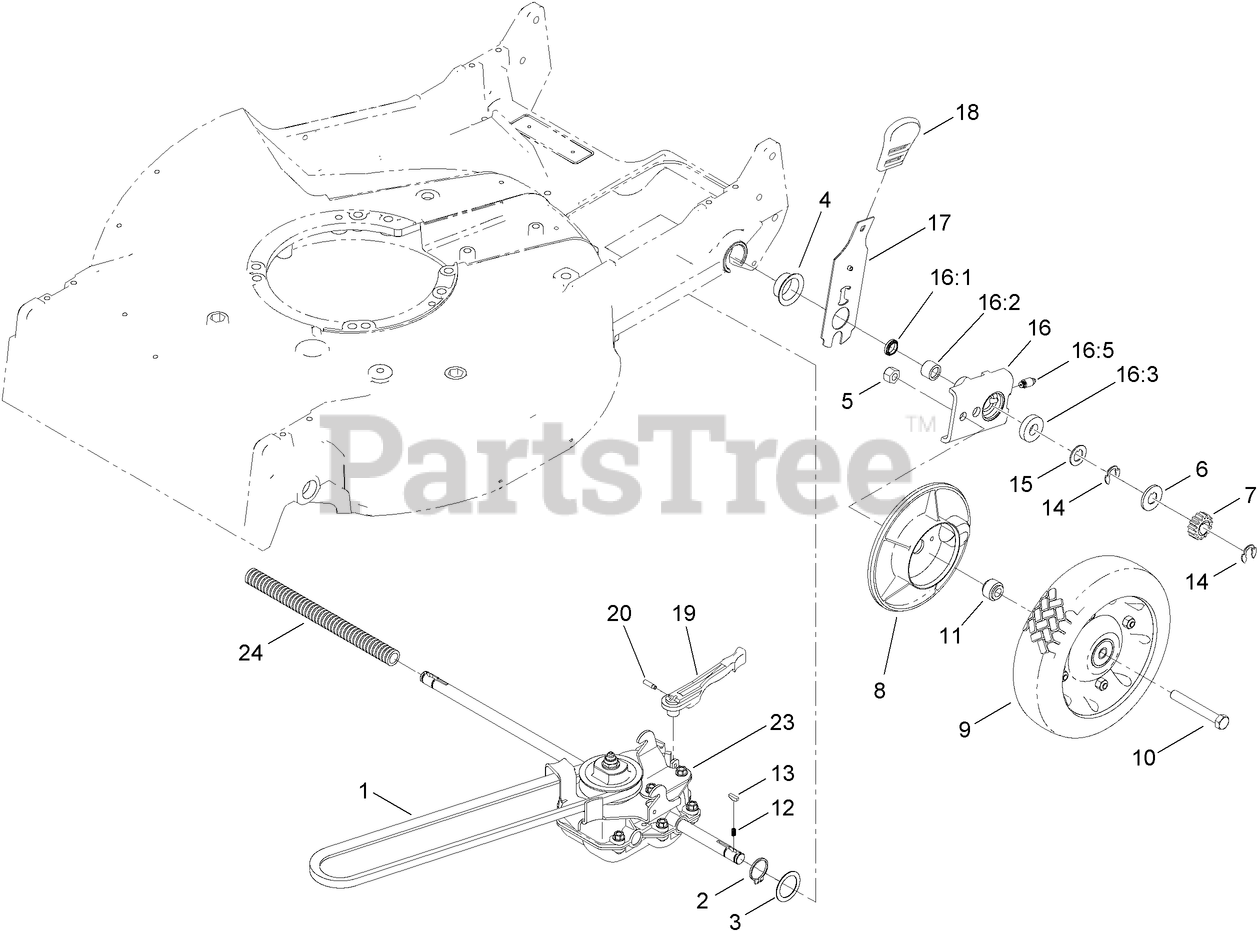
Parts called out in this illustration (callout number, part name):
1	V-BELT
2	RING-RETAINING
3	WASHER
4	CAP-END
5	NUT-LOCK, CONE
6	WASHER-THRUST, OUTER
7	GEAR-PINION
8	COVER-WHEEL
9	WHEEL AND TIRE ASM
10	SCREW-HH
11	SPACER-COVER, WHEEL
12	SPRING-COMPRESSION
14	RING-RETAINING
15	WASHER-THRUST, OUTER
16	PIVOT ARM ASM
16:1	SEAL-OIL
16:2	BEARING-CAGED NEEDLE ROLLER
16:3	BEARING-WHEEL
17	REAR SPRING ARM ASM
18	KNOB-HOC
19	LEVER-SHIFT
20	PIN-SPRING
23	GEAR CASE ASM
24	COVER-SHAFT, DRIVE
